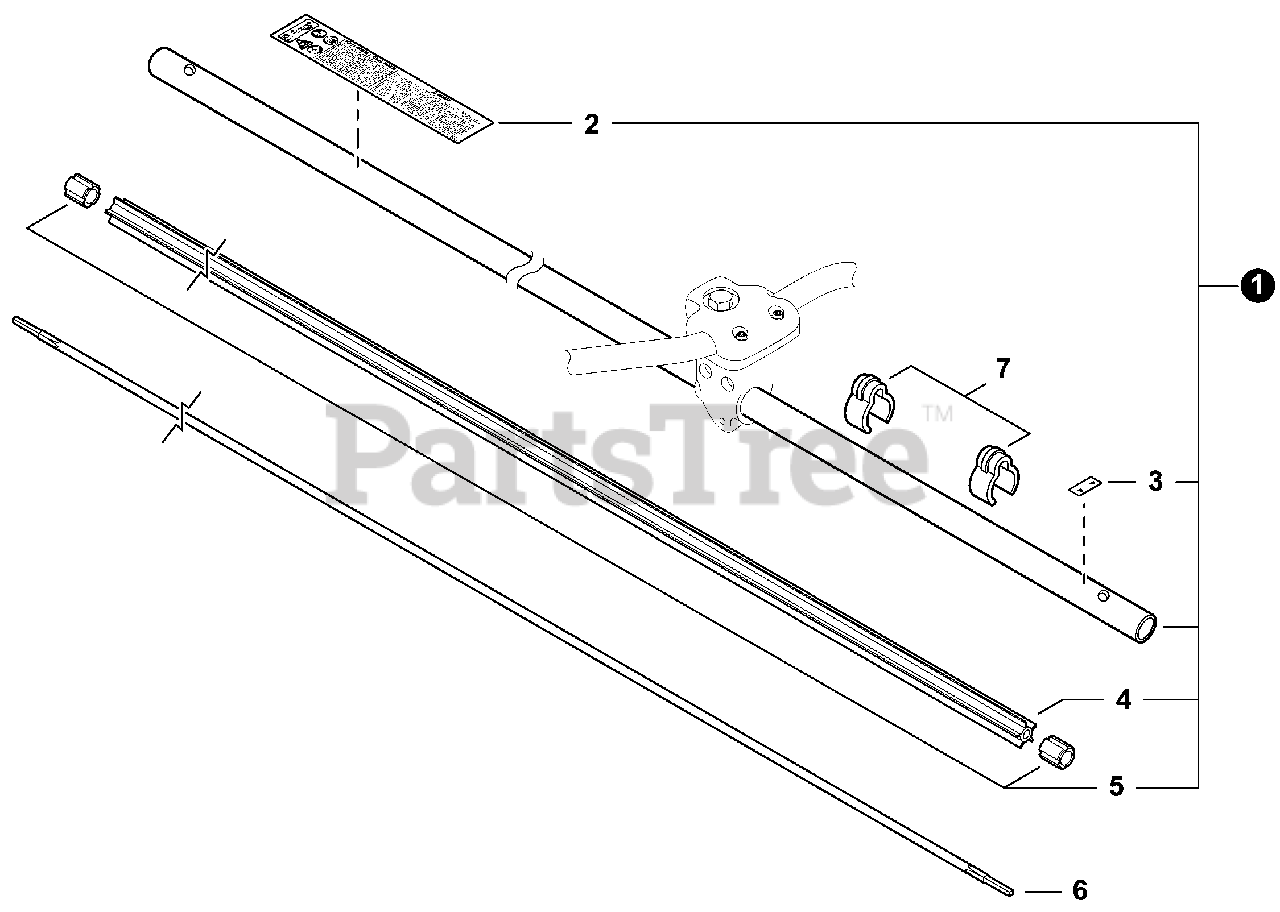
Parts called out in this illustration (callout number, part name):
1	MAIN PIPE ASSY
2	LABEL, CAUTION
3	LABEL - ALIGNMENT
4	LINER, FLEXIBLE 21.6×1420
6	DRIVESHAFT - FLEXIBLE L= 1522
7	CLIP, CABLE 25MM
